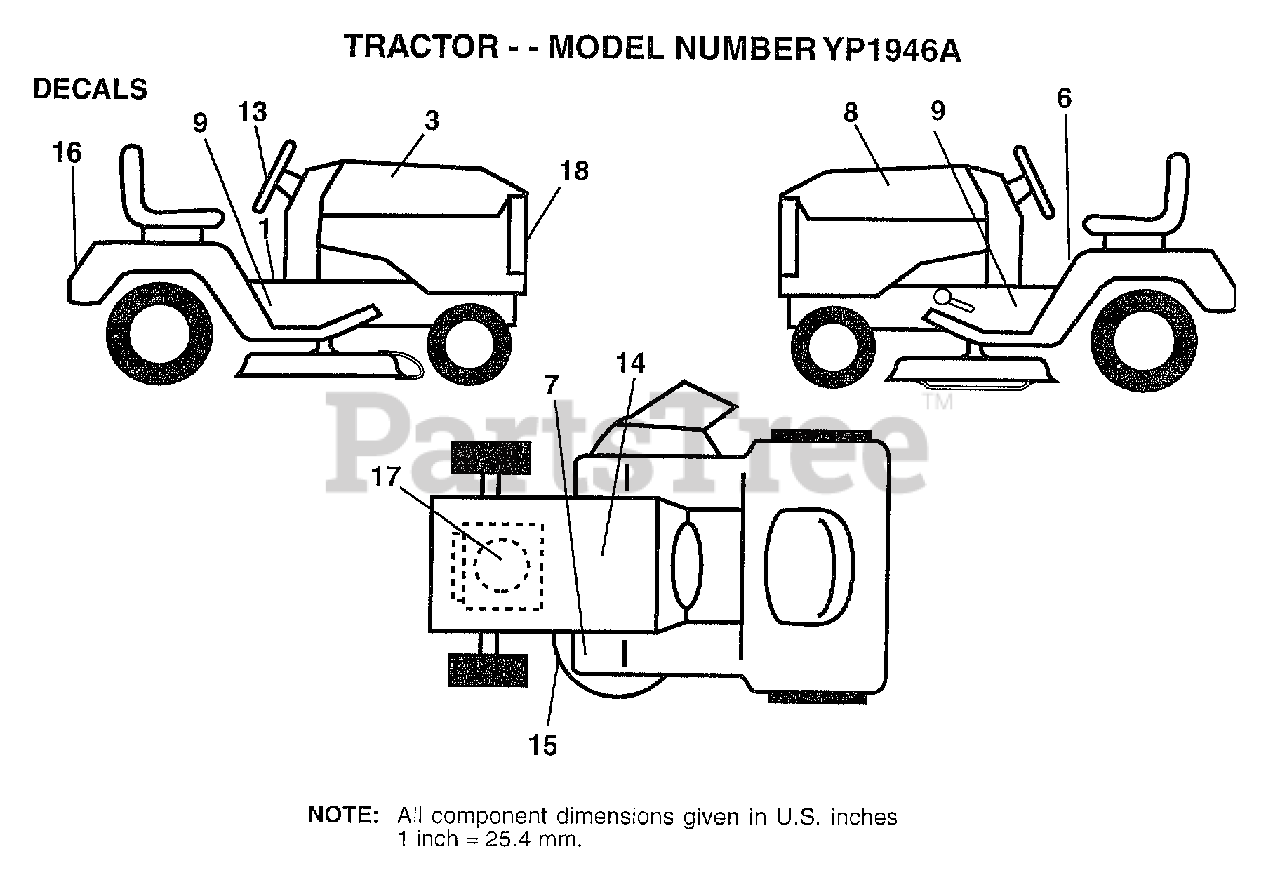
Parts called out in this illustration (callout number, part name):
1	"DECAL DASH,OPER."
3	"DECAL HOOD,RH 19H"
6	"DECAL DANGER,FEND"
8	MANL.P.YP6Y22CHA
9	"DECAL CHASSIS,46"""
13	DECAL INS STRG WH
14	DECAL.BATRY.3-3908
15	"DECAL.V.BELT.44"""
16	DECAL FENDER
17	DECAL, HP ENGINE
